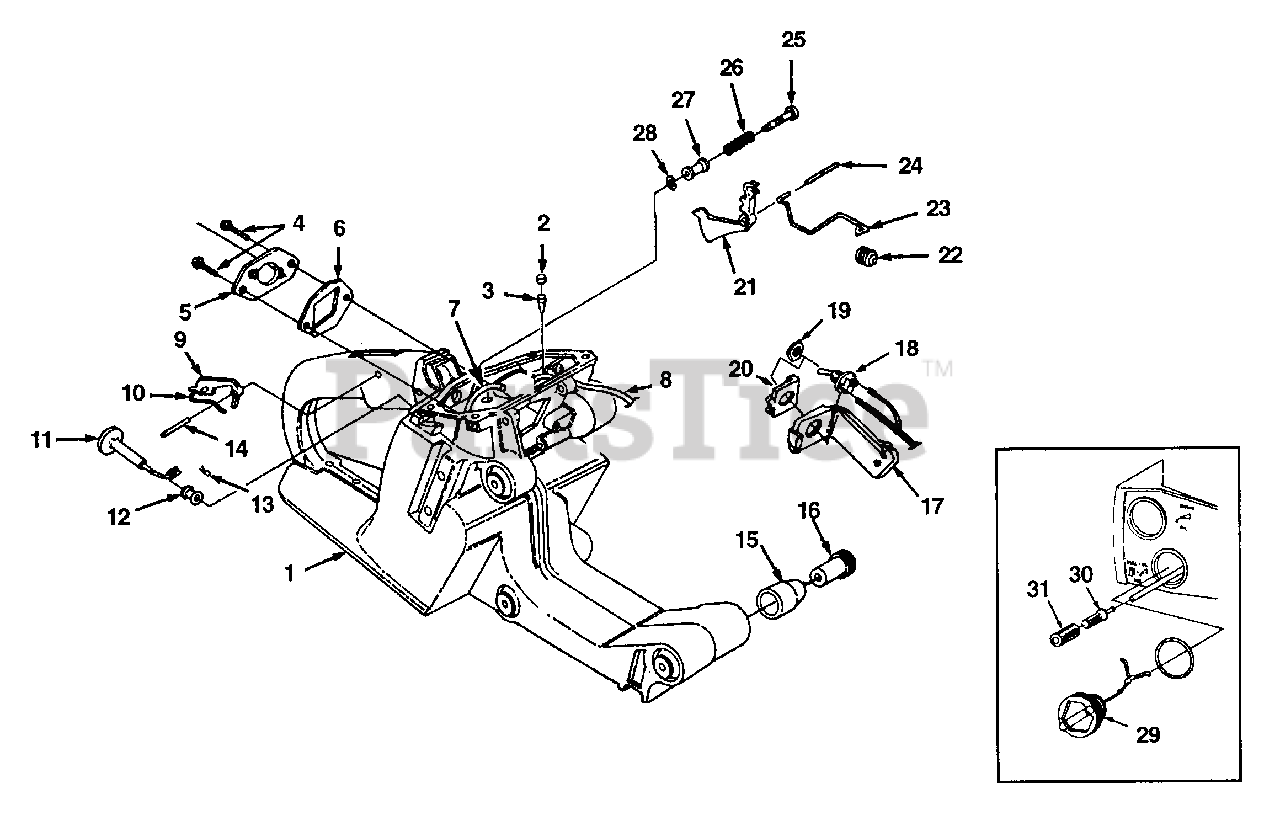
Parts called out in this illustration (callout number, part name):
1	HOUSING-Engine
2	TANK VENT FILTER
3	VALVE-Duck Bill
4	SCREW-Torx Truss (10-24 x 1/2")
5	ADAPTOR-Carburetor
6	GASKET-Carburetor
7	TUBING-Rubber (Fuel Line, 9 1/2")
8	TUBING-Rubber (Pulse Line, 6 1/2")
9	TRIGGER-Lock
10	SPRING-Flat
11	ROD-Choke
12	GROMMET
13	PIN-Cotter
14	PIN-Trigger
15	ISOLATOR-Vibration
16	SLEEVE-Flanged
17	COVER, Switch
18	SWITCH-Toggle
19	NUT-Hex
20	PLATE-Indicating
21	TRIGGER-Throttle
22	BOOT-Throttle Rod
23	ROD-Throttle
24	PIN-Trigger
25	PIN-Throttle Lock
26	SPRING-Compression
27	BUSHING-Flanged
28	RING-Retaining
29	FUEL CAP
30	FUEL FILTER
31	FILTER ELEMENT
